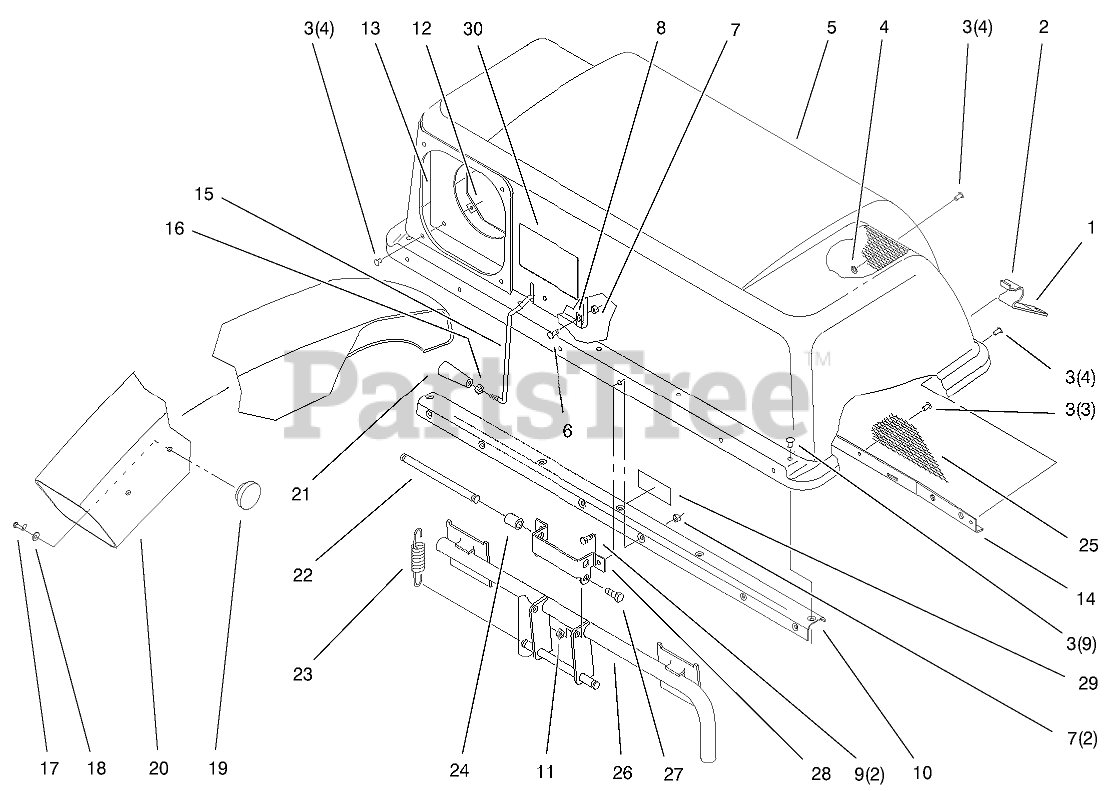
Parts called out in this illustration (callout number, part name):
2	LATCH-BAGGER, TOP
3	RIVET-BLIND
4	WASHER-FLAT
5	TOP-BAGGER
6	SCREW-HH
7	NUT-LOCK, NI
8	CLAMP
9	SCREW-HH
10	Stiffener ASM (OnlyOn: 79310)
10:1	Decal-Caution (OnlyOn: 79310)
11	NUT-LOCK, NI
12	CLAMP-SEAL
13	SEAL-CHUTE
14	SUPPORT-SCREEN
15	FEELER-FILL, BAG
16	NUT-JAM
17	SCREW-PPHTF
18	WASHER-PLAIN
20	CHUTE-DISCHARGE
21	HANDLE-TAPERED
22	PIN-SPRING
23	SPRING-EXTENSION
24	Spacer
25	SCREEN-BAGGER
26	FRAME ASM
27	SCREW-HH
28	Hinge-Bag, Top
30	Decal-Easy Twin(Only On: 79310)
30	Decal-Easy Twin(Only On: 79448)
